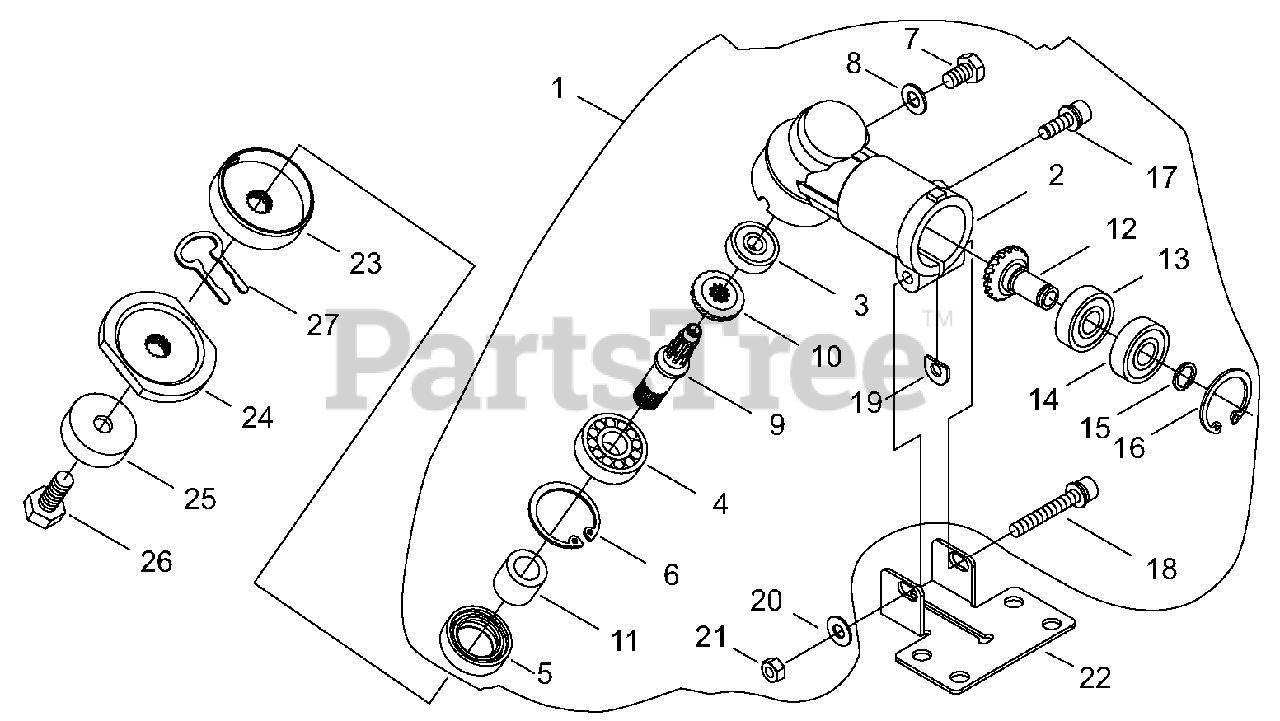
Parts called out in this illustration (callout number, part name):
1	GEAR CASE ASSY
2	CASE, GEAR
3	BEARING, BALL - 626
4	BEARING, BALL - 6000
5	SEAL, OIL
6	RING, RETAINING - 26
7	BOLT - 6X10
8	WASHER - 8
9	GEAR - SHAFT
10	GEAR - BEVEL
11	COLLAR
12	GEAR - SHAFT
13	BEARING, BALL
14	BEARING, BALL - 608ZZ
15	RING, RETAINING
16	RING, RETAINING - 22
17	SCREW - 5X16
18	SCREW - 5X35
19	SHIM
20	WASHER - 5
21	NUT - 5
22	CLAMP - LOWER
23	ADAPTOR, BLADE - UPPER
24	ADAPTOR, BLADE - LOWER
25	GUARD
26	BOLT - 7X18 -- LEFT HAND
27	CLIP
